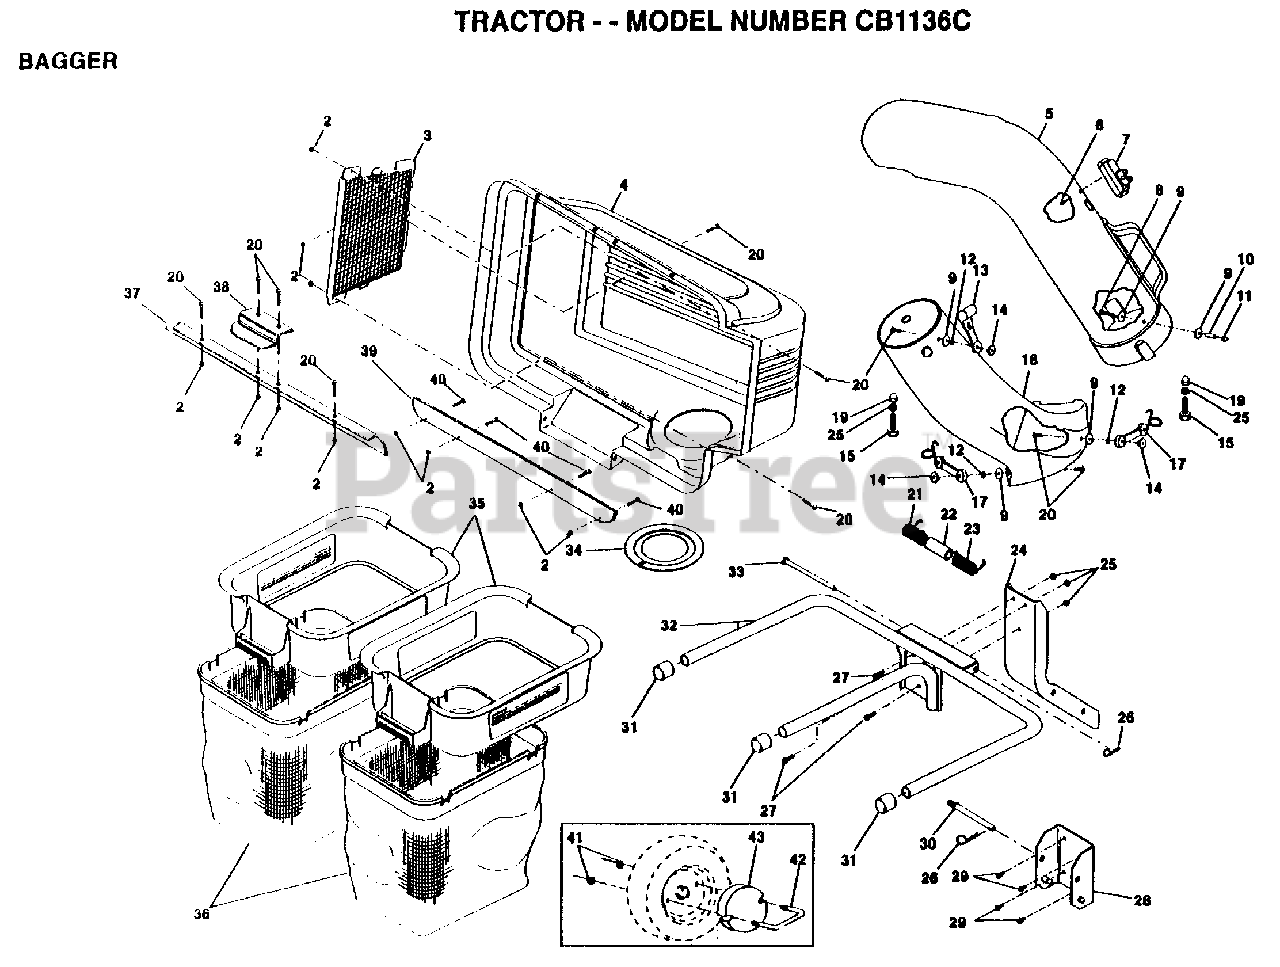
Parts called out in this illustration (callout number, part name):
2	LOCKNUT
3	COVER.SCREEN.
5	CHUTE.UPPER.BAGGE
6	SPECIAL SCREW
7	INDICATOR.DUMP.BG
9	WASHER #10
10	SPACER LT
11	ACORN NUT RB
12	LOCKWASHER
13	HOOD LATCH T
14	WELDNUT
18	"CHUTE.LOWER.36"""
19	ACORN NUT
20	SCREW
21	SPRING.COVER.LH
22	SPACER.COVER.BAGG
23	SPRING COVER RH
24	POST SUPPORT
27	BOLT
28	BRACKET.MTG.BAGGE
29	SCREW LT
30	PIN.SUPT.POST
31	CAP TUBING END
32	FRAME. BAGGER
33	HINGE PIN
34	GASKET.COVER.BAGG
35	CONTAINER.TOP.BAG
36	CONTAINER BOTTOM
37	SEAL.COVER.BAGGER
38	LATCH HANDLE
40	SCREW #10-24X12
41	NUT
43	"WEIGHT,FRT WHEEL"
